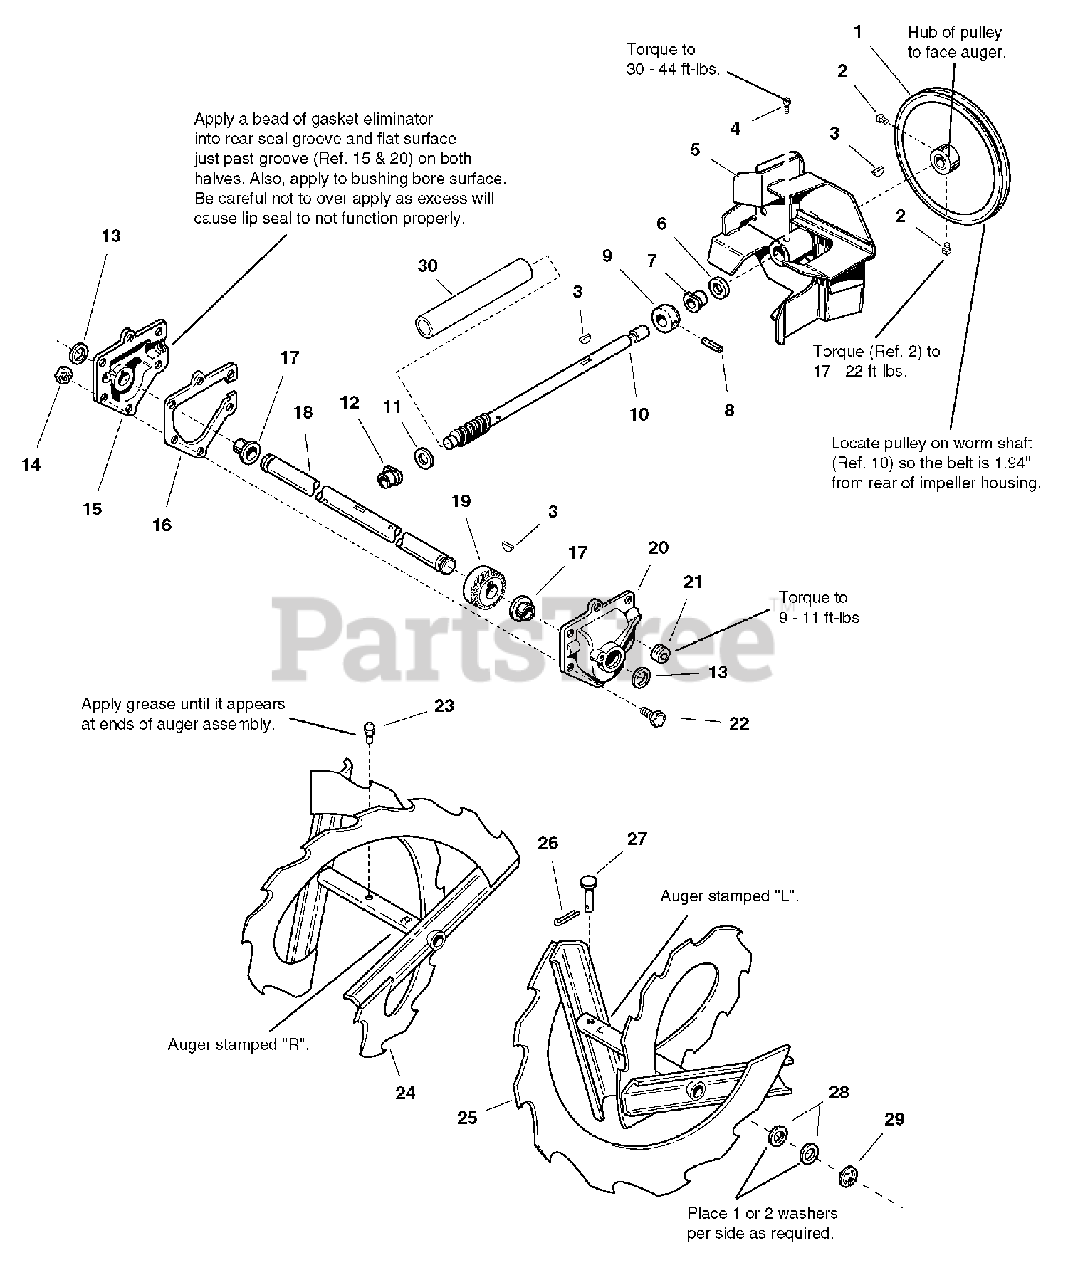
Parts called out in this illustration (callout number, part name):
1	PULLEY, Auger Drive
2	SETSCREW, Square Head Cup Point, 3/8-18 x 5/8
3	KEY, Woodruff, 3/16 x 3/4
4	SETSCREW, Square Head Cup Point, 3/8-16 x 1/2
5	IMPELLER
8	PIN, Drive-Lock 3/16 x 1-1/2
9	THRUST COLLAR
10	SHAFT, Worm
11	WASHER, Thrust
14	NUT, Lock, 1/4-20
15	GEAR CASE COVER, R.H.
18	SHAFT, Auger
20	GEAR CASE COVER, L.H.
21	PIPE PLUG, 1/8 NPT
22	CAPSCREW, Hex Head, 1/4-20 x 7/8
23	GREASE FITTING
24	AUGER, R.H. 22", Serrated
25	AUGER, L.H. 22", Serrated
26	PIN, Cotter 3/32 x 3/4
27	PIN, Shear
28	WASHER
29	RING, Retaining
